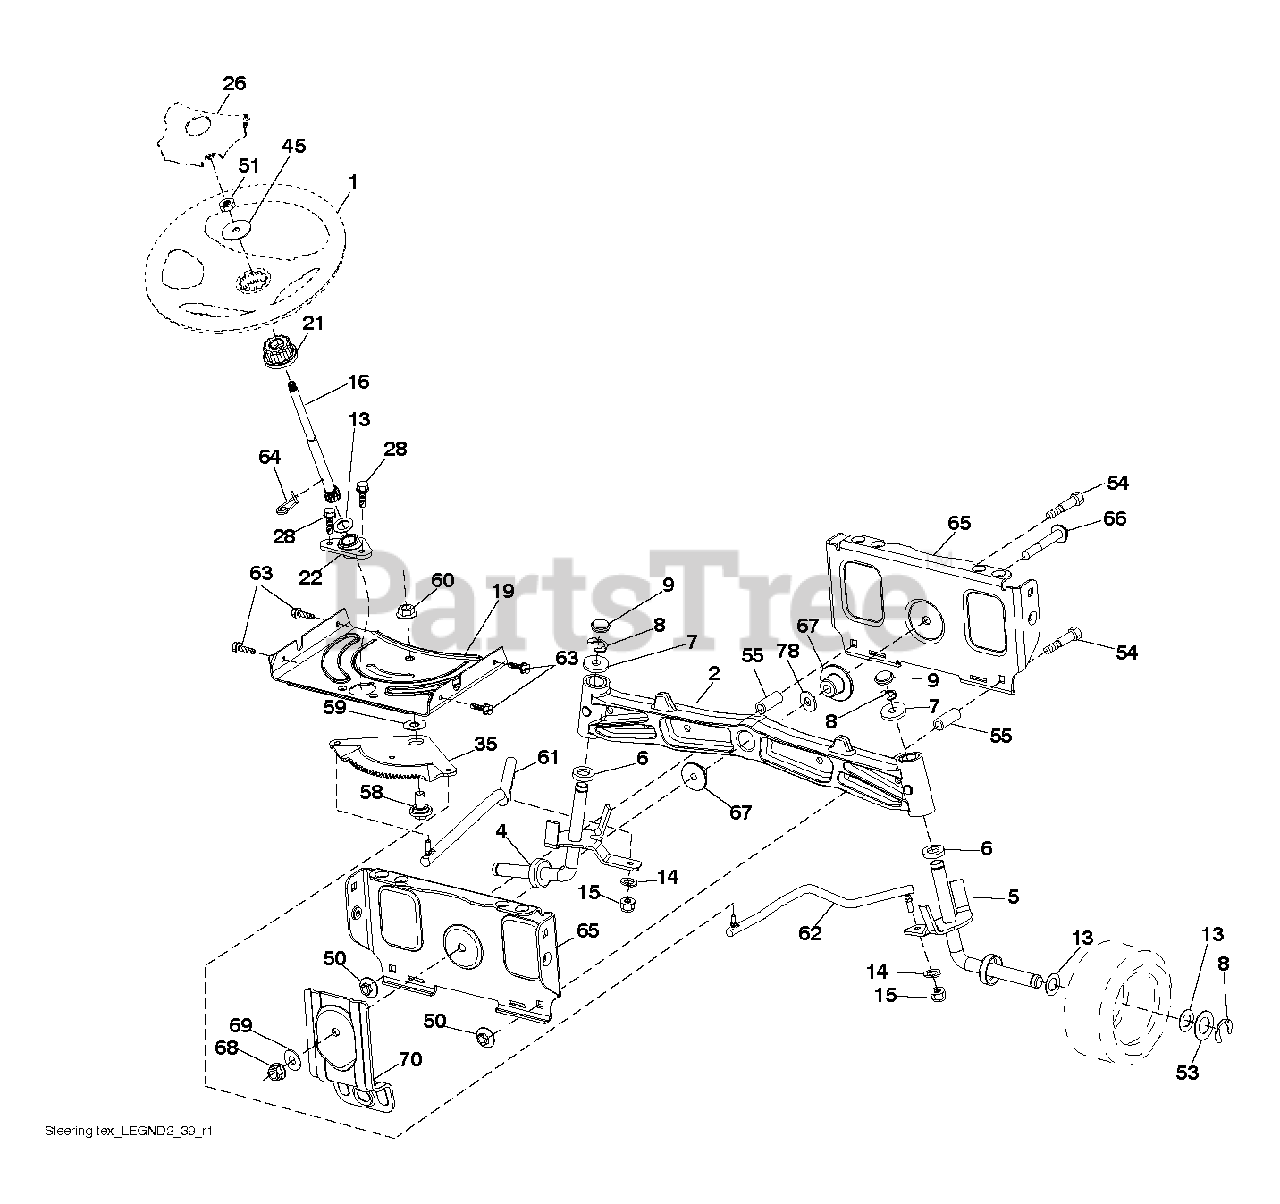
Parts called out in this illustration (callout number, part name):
1	WHEEL.STEER.HUSQ.SR.498.OVMLD
2	AXLE.CAST.IRON
4	SPINDLE.WELDED.LH.16"TEX
5	SPINDLE.WELDED.RH.16"TEX
6	THRUST WASHER
9	CAP.SPINDLE.BLACK
14	WASHER, LOCK 3/8
15	NUT CROWNLOCK 3/8-24
16	SHAFT, STEERING
19	PLATE.STEER.DDL.NLT/NG
21	ADAPTER, WHEEL STNG..
22	STEERING.SUPT.LOWER.
26	INSERT.CAP.WHL.STRG.HUSQ.PREM
28	SCREW, 3/8-16X3/4
35	GEAR.SECTOR.PLATE.DDL.
45	WASHER 9/16"ID, 2 3/8"OD
50	NUT LOCK FLG 3/8-16 UNC
51	NUT.HEX.1/2-20
53	WASHER.HARDENED
55	SPACER.BRACE.AXLE
58	BOLT.SHOULDER.SECTOR.P
59	WASHER.THURST.SECTOR.S
60	NUT FLANGE LOCK 5/8-11
61	DRAGLINK.LH.BALLSTUD.D
62	DRAGLINK.RH.BALLSTUD.D
63	SCREW
64	RETAINER.CLIP.SPRING.S
65	BRACE.AXLE.FRONT.NLT/N
66	BOLT HEX FGHD 7/16-14 X 3 SERR
67	BUSHING.PM.FRONT AXLE
68	NUT.LOCK.FLANGE.7/16
69	WASHER.1.5X.505X.118
70	BRKT.DECK.SUSPENSION.F
78	THRUST WASHER
